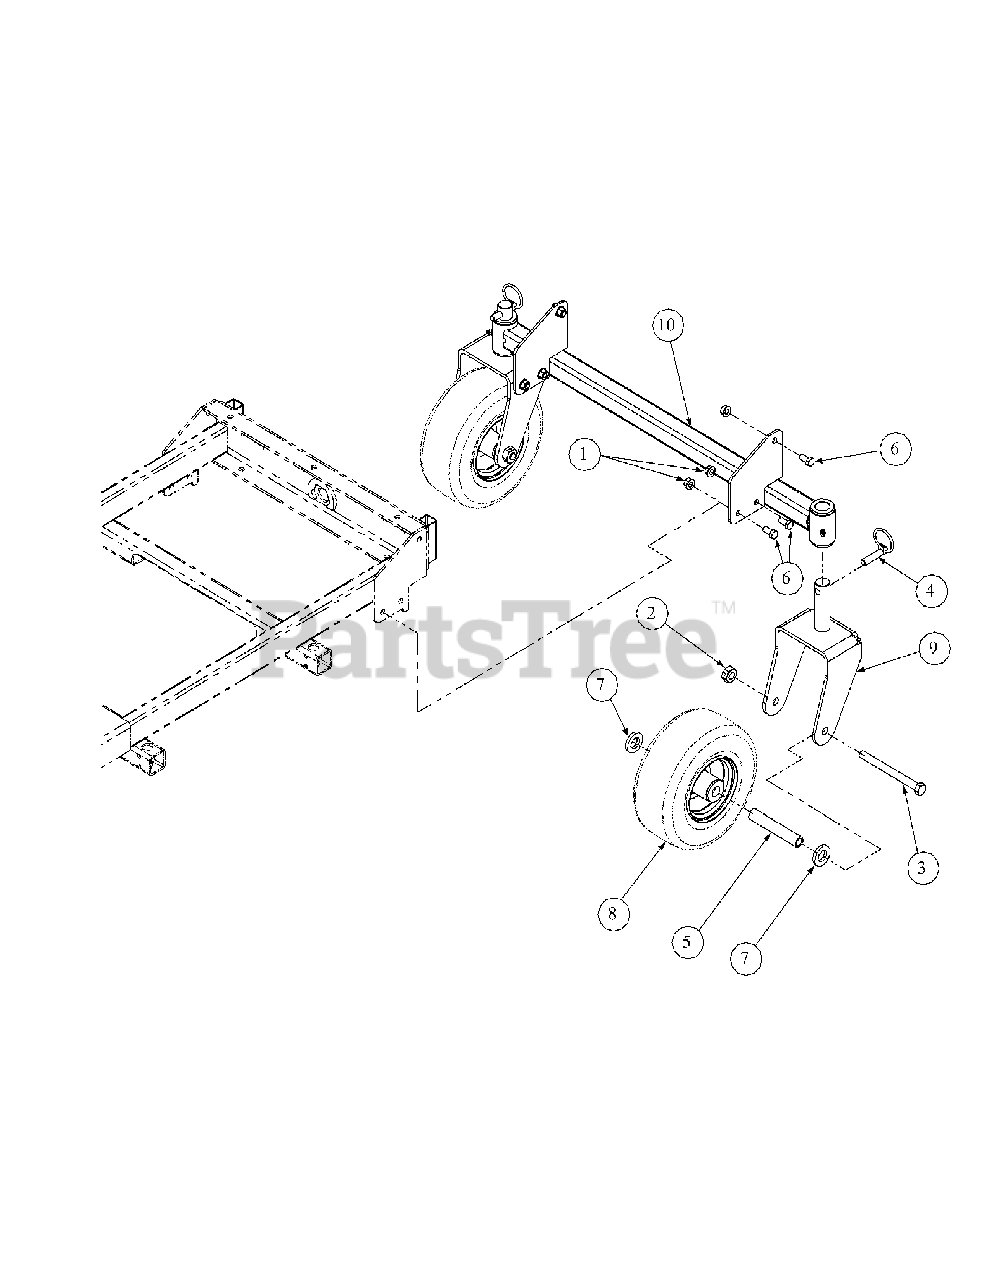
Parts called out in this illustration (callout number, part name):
1	Nut, 3/8-16, Hex Flange Lock
2	Nut, 1/2-20, Center Lock
3	Hex Cap Screw, 1/2-20 x 5.50
4	Klik Pin, 1.75 Long
5	Spacer Wheel
6	Hex Cap Screw, 3/8-16 x .750
7	Spacer, .812 ID x .218 Long
8	Wheel Assembly, 9 x 3.50-4
9	Caster Arm Weldment
10	Caster Mount Bracket Assembly
